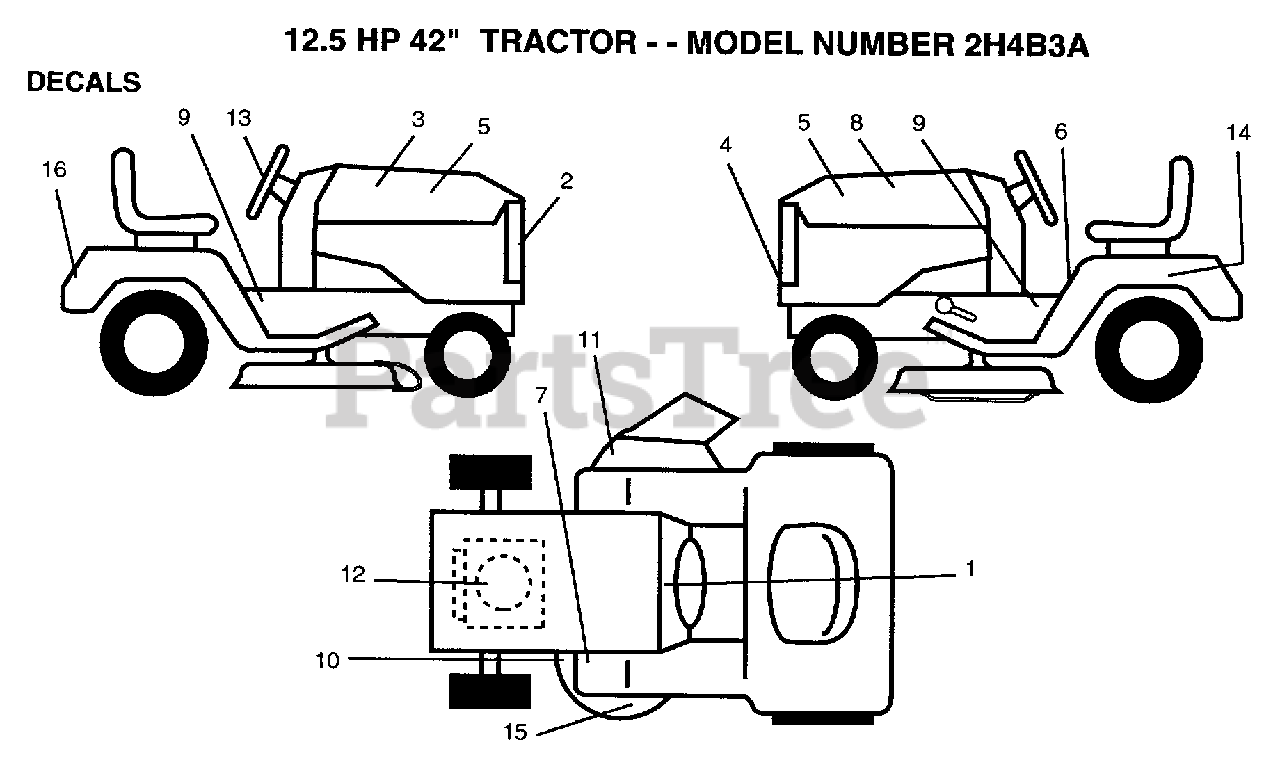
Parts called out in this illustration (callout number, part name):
2	GRILL DECAL
6	DECAL CAUTION
7	DECAL T
9	CHASSIS DECAL
10	DECAL
11	"DECAL, WARNING"
12	DECAL.ENG.272632
13	"DECAL,STR WHL"
14	DECAL
16	FENDER DECAL
